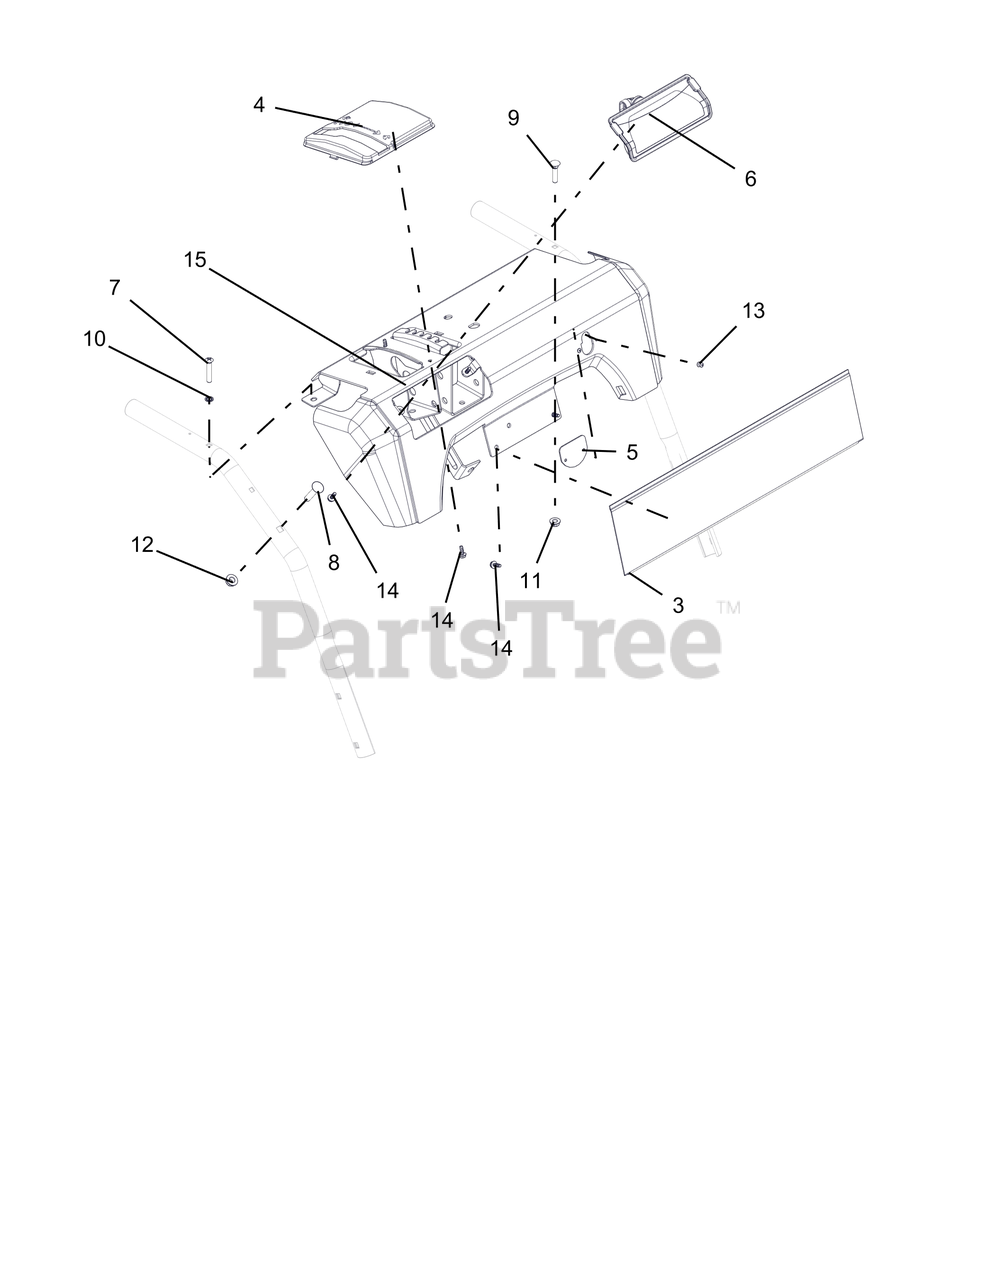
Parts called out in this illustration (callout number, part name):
3	WLDMT, BRAND PLATE
4	BEZEL, HYDRO SHIFT BRUSH
5	COVER, DASH BRKT, BRUSH
6	ASM, HEADLAMP - HALOGEN 15W - 2 SHOT
7	SCR, -- MCH .25-20X1.50 OVAL HD
8	BLT-RDHDSQNK .31-18X1.50 G5 YWZC
9	BLT, RDHDXLSQNK .25-20X1.25 G5YZ
10	WSHR, LK-INT .250 TH TYA
11	NUT, LK-CTR-FLG .25-20 YWZC
12	NUT, LK-TOP-FLG .312-18 YWZC
13	RVT-POP #43 .125x.313 STL ZINC
14	SCR-TAP #10X.500 BOSS INDHXHD
15	DASH, SERVICE - 08000924 DECAL
